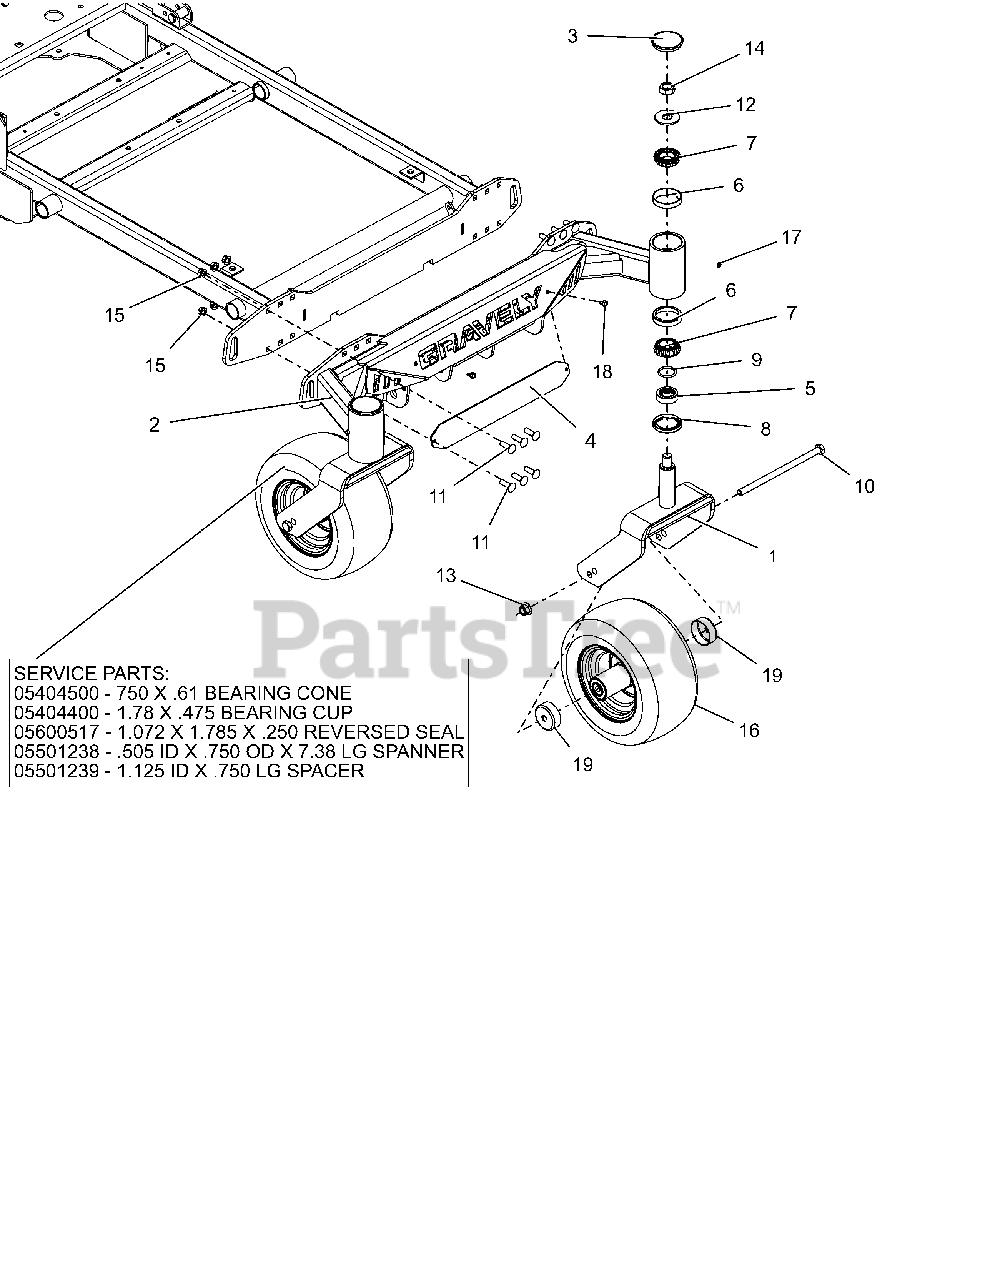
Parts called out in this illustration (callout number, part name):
1	CASTER FORK WMT - RED
2	WMT, 48 FRONT AXLE
3	CAP, DUST
4	BACKER, NAMEPLATE
5	SPACER, FRONT CASTER FORK
6	BRG-CUP 2.328X.465
7	BRG-CONE 1.25X.66
8	SEAL, OIL 1.75 X 2.332 X .312
10	@BLT-HEX .50-13X9.00 GR5 YWZC
11	@BLT-RDHDSQNK .38-16X1.25 G5YZ
12	@WSHR-FL-STL.812X2.00X.148YWZC
13	@NUT-LK-NYL-FLG .50-13 YWZC
14	NUT-JAM TOPLK .75-16 YWZC
15	@NUT-LK-TOP-FLG .38-16 YWZC
16	ASM, WHL/TIRE 13X6.50-6 SEMI-PNEUMATIC
16	BRG-CONE .750X.61
16	BRG-CUP 1.781X.475
16	SEAL, 1.125 X 1.781 X .469
16	SPANNER,.505ID X.750OD X7.38LG
16	SPACER, 1.125 ID X .750 LG
17	FTG, .25-28 FLUSH MNT GREASE
18	SCR-TAP .25-20X.50 HWH TR YWZ
19	SHIELD, WHEEL BEARING
